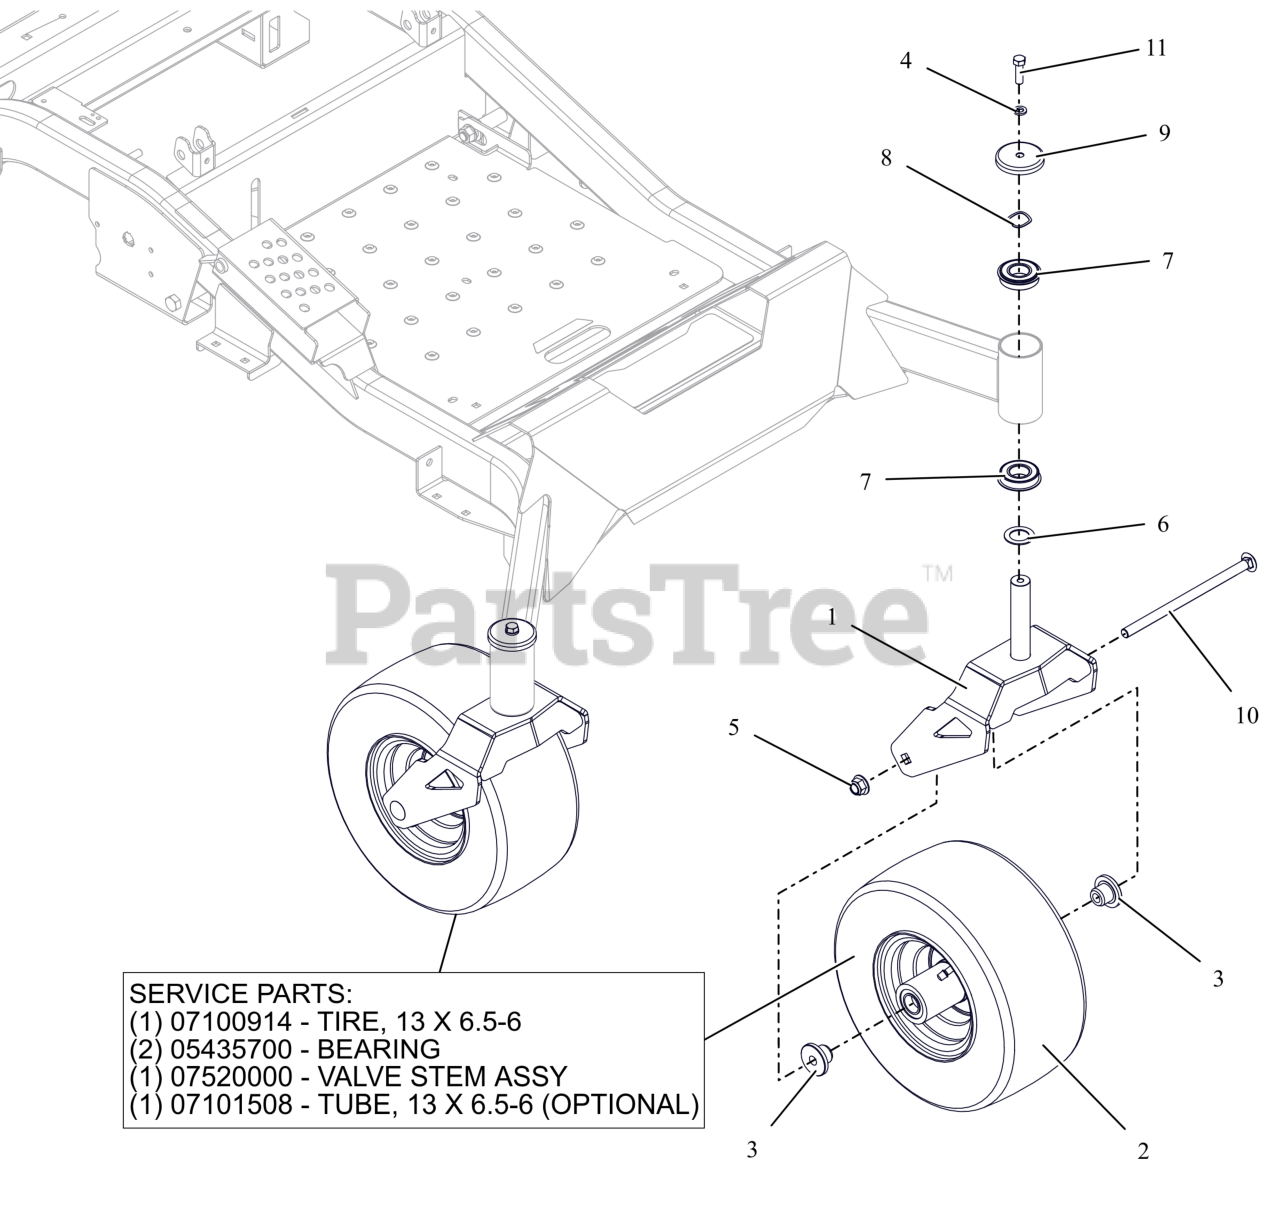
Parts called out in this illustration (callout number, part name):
1	WLDMT- CASTER FORK
2	ASM, TIRE/WHEEL 13 X 6.50-6 BLK RIM
2	LAWN TIRE FRONT, 13X6.50-6 SMOOTH
2	BRG, 25MM ID X 52MM OD X 15MM
2	VALVE STEM ASS'Y
2	TIRE TUBE, 13/6.5-6 4 PLY TR87 90 BENT VALVE
3	SPACER, FRONT WHEEL
4	WSHR-LK-REG .375X.094 ZB500
5	NUT,NYL-FLG .50-13 GF ZCC
6	WSHR-HRD-THRS 1.007X1.542X.062
7	BEARING, BALL -2.000 OD X 1.000 ID X .5625 W/RING
8	WSHR-WAVE 1.0X1.25X.028 .145FH
9	SHIELD, AXLE BEARING
10	BLT-RHSN .50-13X9.00 G5 ZCC NS
11	BLT- HEX .38-16X1.25 G5 ZB500
